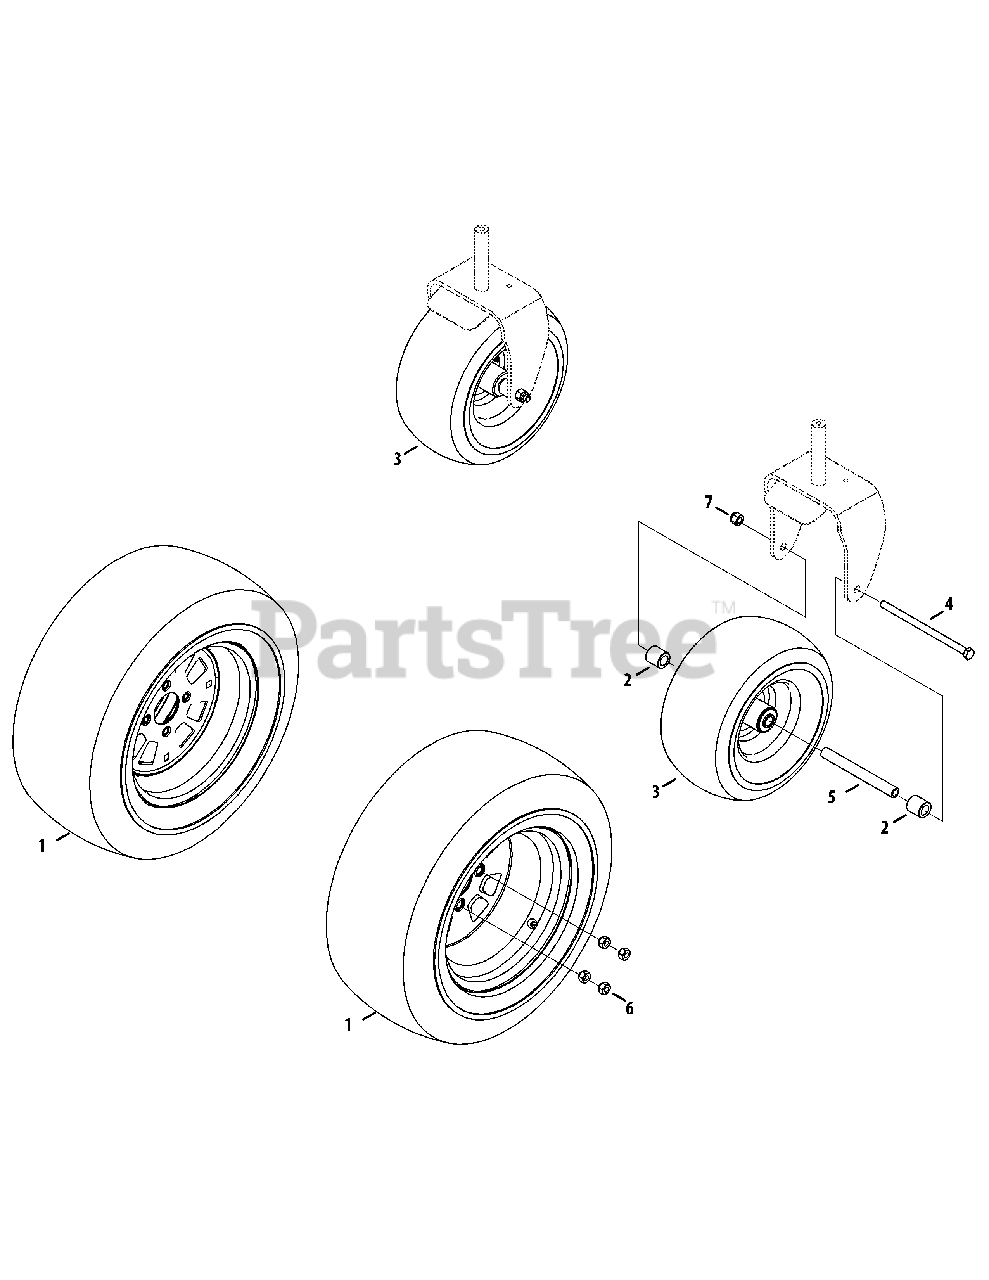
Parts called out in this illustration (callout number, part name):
1	Wheel Assy., 22 x 9.5 x 12
2	Hub, .76 x 1.23 x 1.25
3	Complete Wheel Assy., 13 x 6.5-6
3	Grease Fitting
3	Bearing, Ball .750 x 1.750
4	Hex Screw, 1/2-13 x 8.5
5	Spacer, .51 x .75 x 1.25
6	Lug Nut, 7/16-14
7	Hex Lock Nut, 1/2-13
